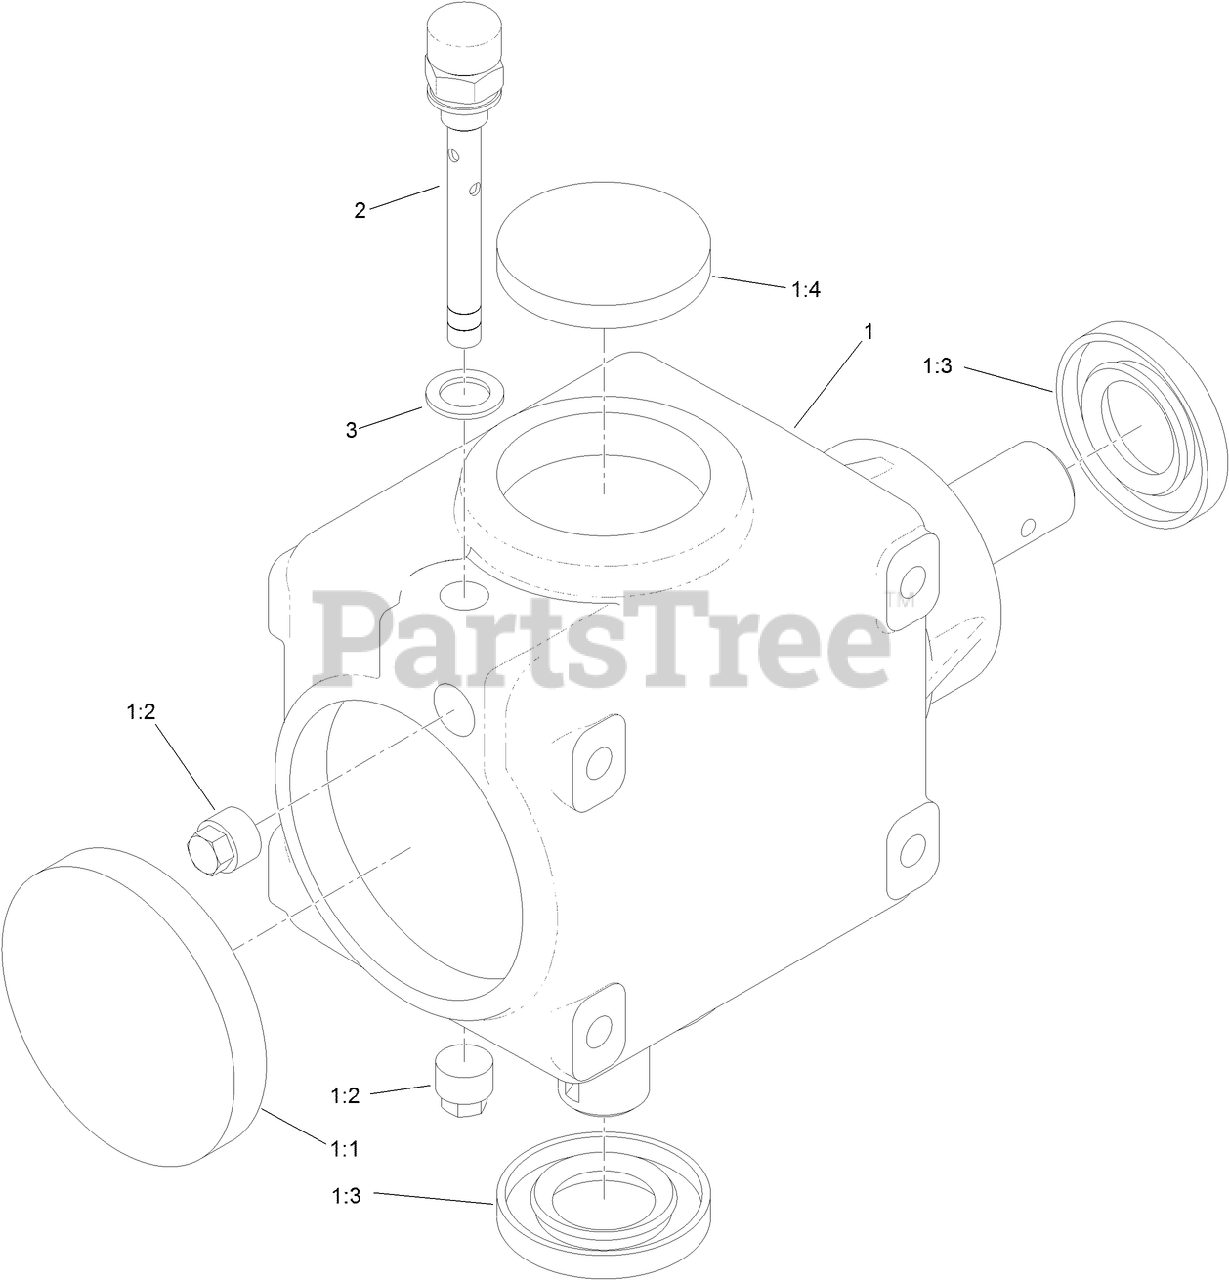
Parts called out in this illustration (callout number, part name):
1	GEARBOX ASM
1:1	CAP-OIL
1:4	CAP-OIL
2	PLUG-BREATHER
3	WASHER
